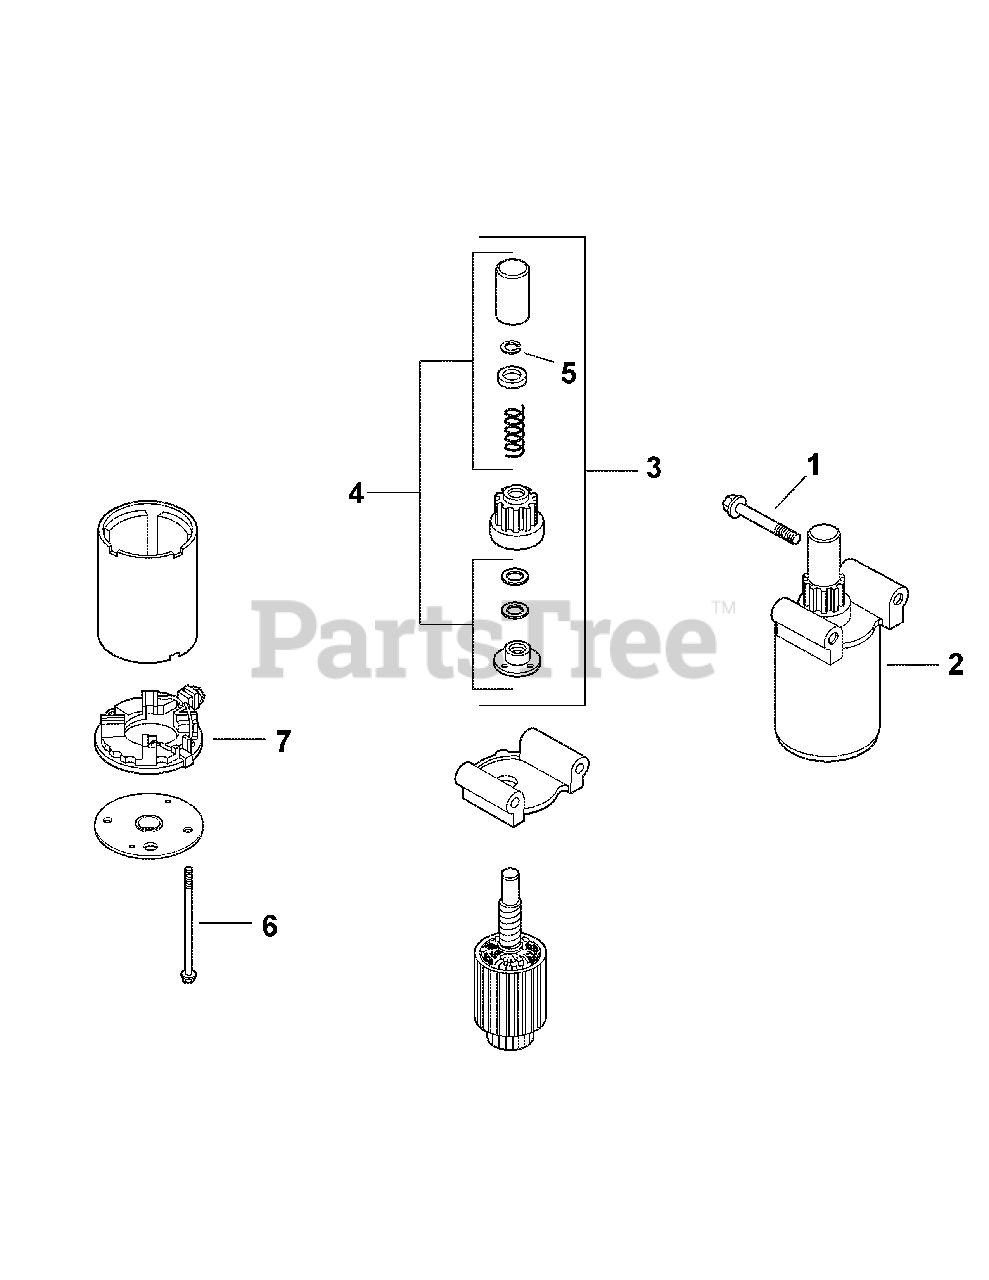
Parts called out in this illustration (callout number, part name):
1	Screw, Flange, M8 x 1.25 x 80
2	Starter Assembly
4	Kit, Drive Parts
5	Ring, Retaining Ring
7	Commutator, End Cap
